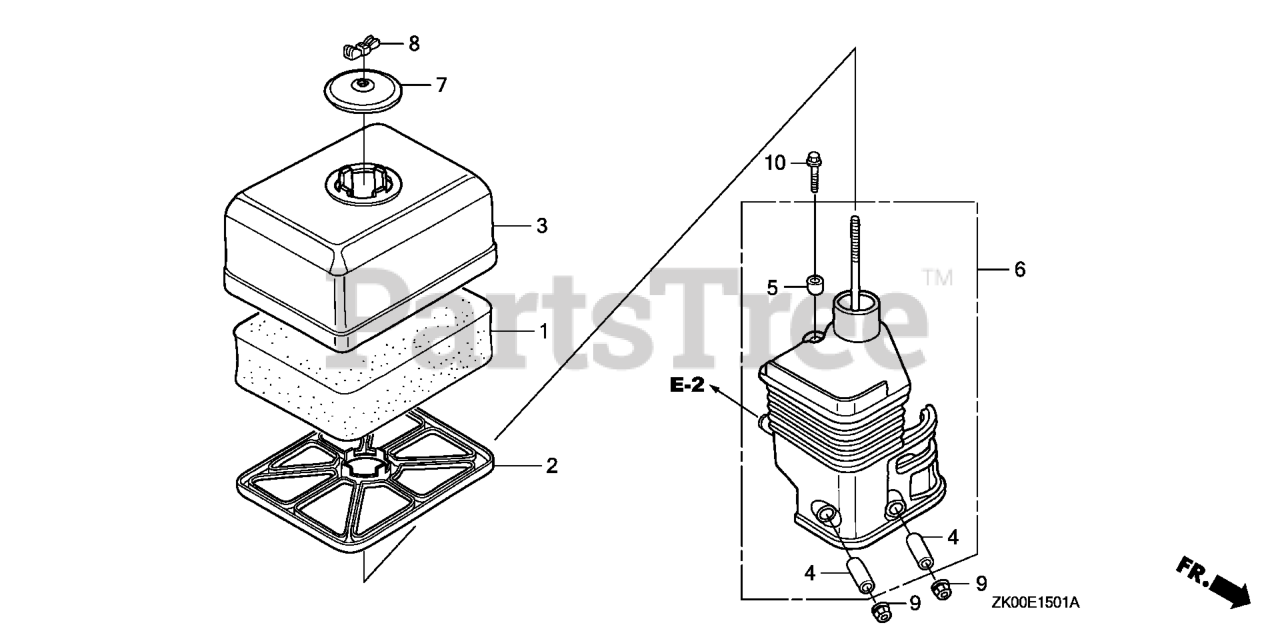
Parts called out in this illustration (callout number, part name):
1	ELEMENT, AIR CLEANER (SEMI-DRY)
2	GRID, AIR CLEANER (SEMI-DRY)
3	COVER, AIR CLEANER (SEMI-DRY)
4	COLLAR, AIR CLEANER Use from Engine SN 1786085.
5	COLLAR B, AIR CLEANER
6	ELBOW, AIR CLEANER
7	CAP, CLEANER
8	WINGNUT, TOOL BOX SETTING
9	NUT, FLANGE (6MM)
10	BOLT, FLANGE (6X20)
